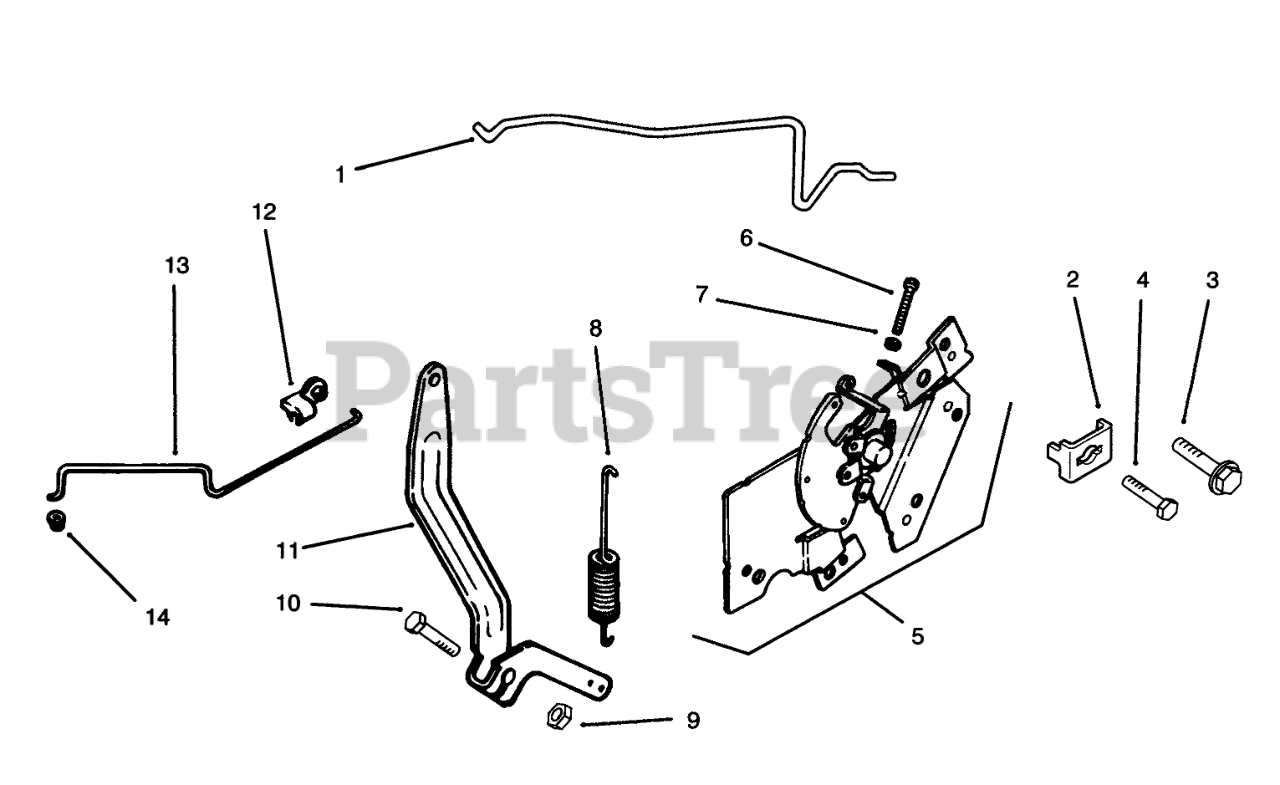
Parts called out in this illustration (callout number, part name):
1	Linkage-Choke
3	Screw
4	Screw-HF
5	Control-ASM INC 6-7
6	Screw
7	Nut
8	Spring Governor
9	Nut
10	Screw
11	Lever
12	Bushing-Linkage
13	Linkage-Throttle
14	Bushing
